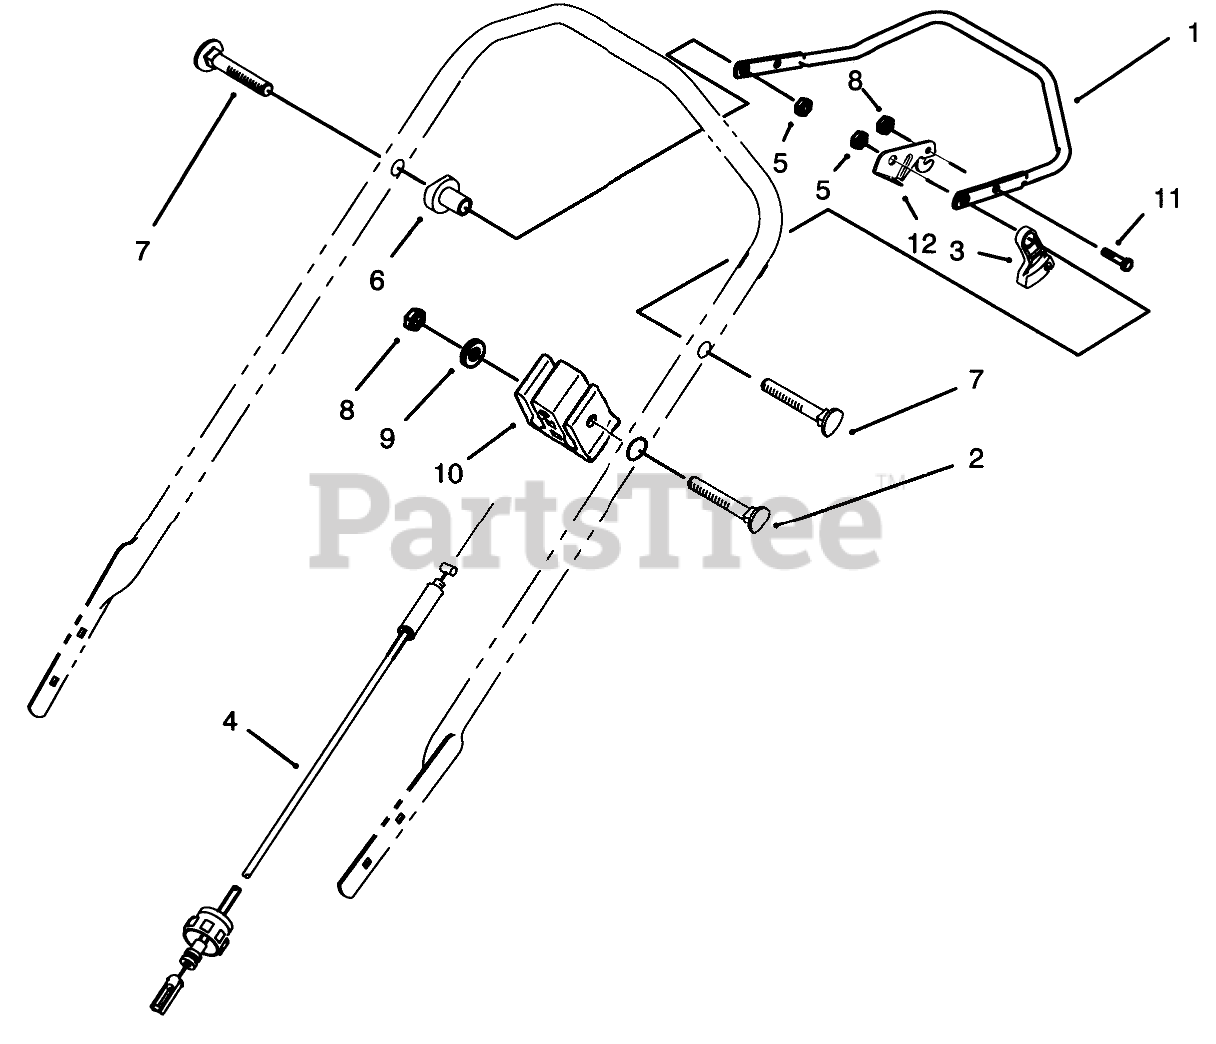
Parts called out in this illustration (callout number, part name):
1	Bar-Control
2	SCREW-HANDLE
3	LEVER-TRACTION
4	TRACTION CABLE
5	NUT-LOCK, NI
6	SPACER-SUPPORT
7	SCREW-HANDLE
8	NUT-LOCK, NI
9	WASHER-FLAT
10	SUPPORT-CABLE
11	SCREW-HH
12	CONTROL LEVER
